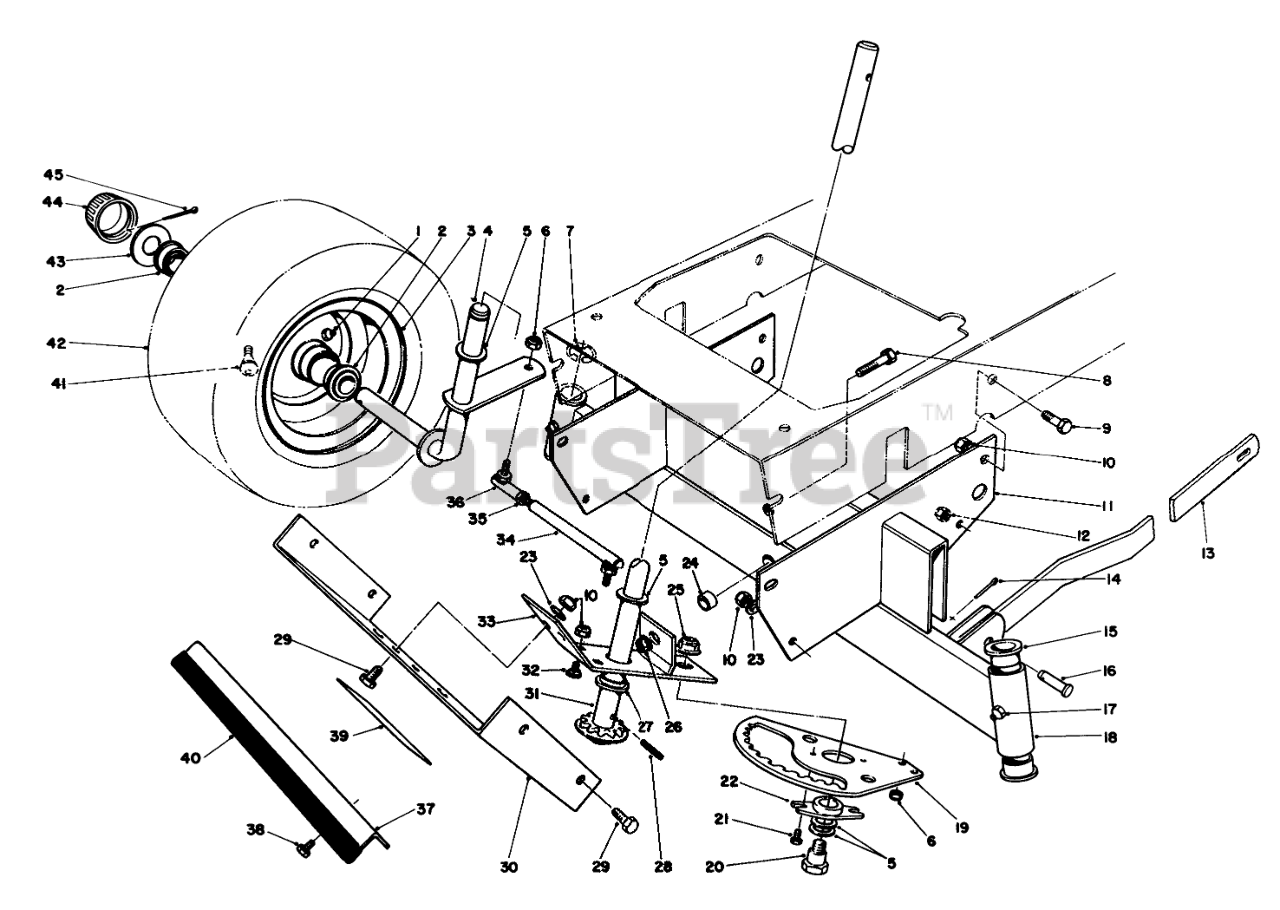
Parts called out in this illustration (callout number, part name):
1	FITTING-GREASE
2	Bearing
4	Spindle-R.H.
5	WASHER-THRUST
7	E-Ring
8	SCREW-HH
9	SCREW-HH
10	NUT-LOCK, NI
11	Support-Front Axle
12	NUT-LOCK, CONE
13	Arm-Suspension, Front
14	PIN-COTTER
15	BEARING-FLANGE
16	PIN-CLEVIS
17	GREASE FITTING
18	Axle-Front (Incl. Ref. #15 & 17)
19	STEERING RACK B
21	SCREW
22	BUSHING-SECTOR
23	WASHER-PLAIN
24	SPACER-AXLE, FRONT
25	NUT-HF
26	NUT-HF
27	BEARING-FLANGE
28	PIN-ROLL, SLOTTED
29	SCREW-HH
30	Cover-Front
31	STRG SHAFT WA
32	SCREW-CARR
33	STRG RACK BRKT WA B
34	Tie Rod-Steering (Incl. Ref. #35 & 36)
35	NUT-JAM
36	JOINT-BALL
37	FRONT GUARD R
38	SCREW-HWHTF
39	Decal-Warning
40	TRIM-FRONT GUARD
41	STEM-VALVE
42	TIRE,PNEU.11X4.00X5
43	WASHER-PLAIN
44	Cap-Hub
45	PIN-COTTER
